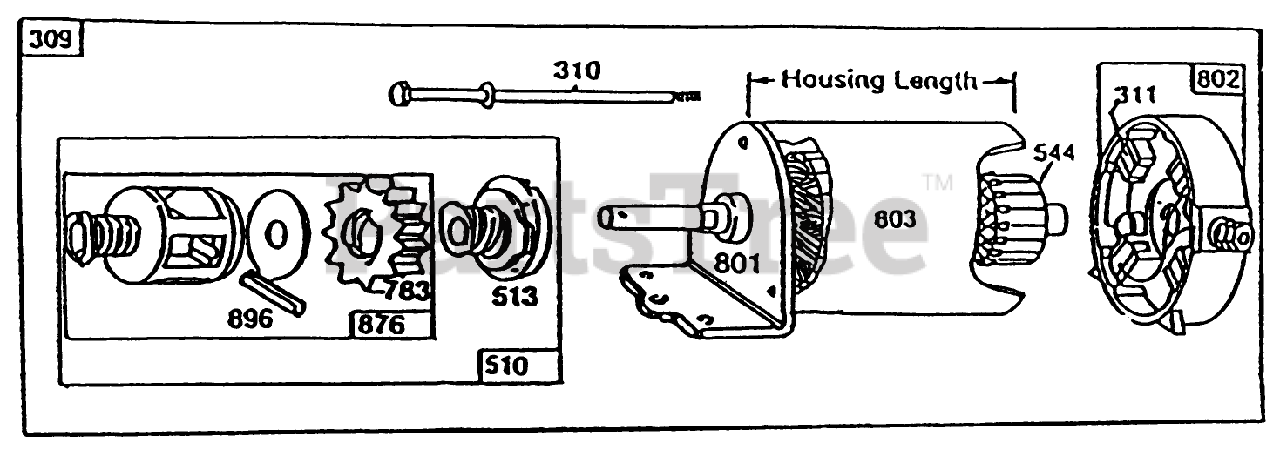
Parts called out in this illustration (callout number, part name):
309	Motor-Starter
310	Thru Bolt Assembly
311	Brush Set
510	Drive Assy.
544	Armature-Starter
801	Drive End Cap Assembly
802	Cap-End
803	Housing Assembly
